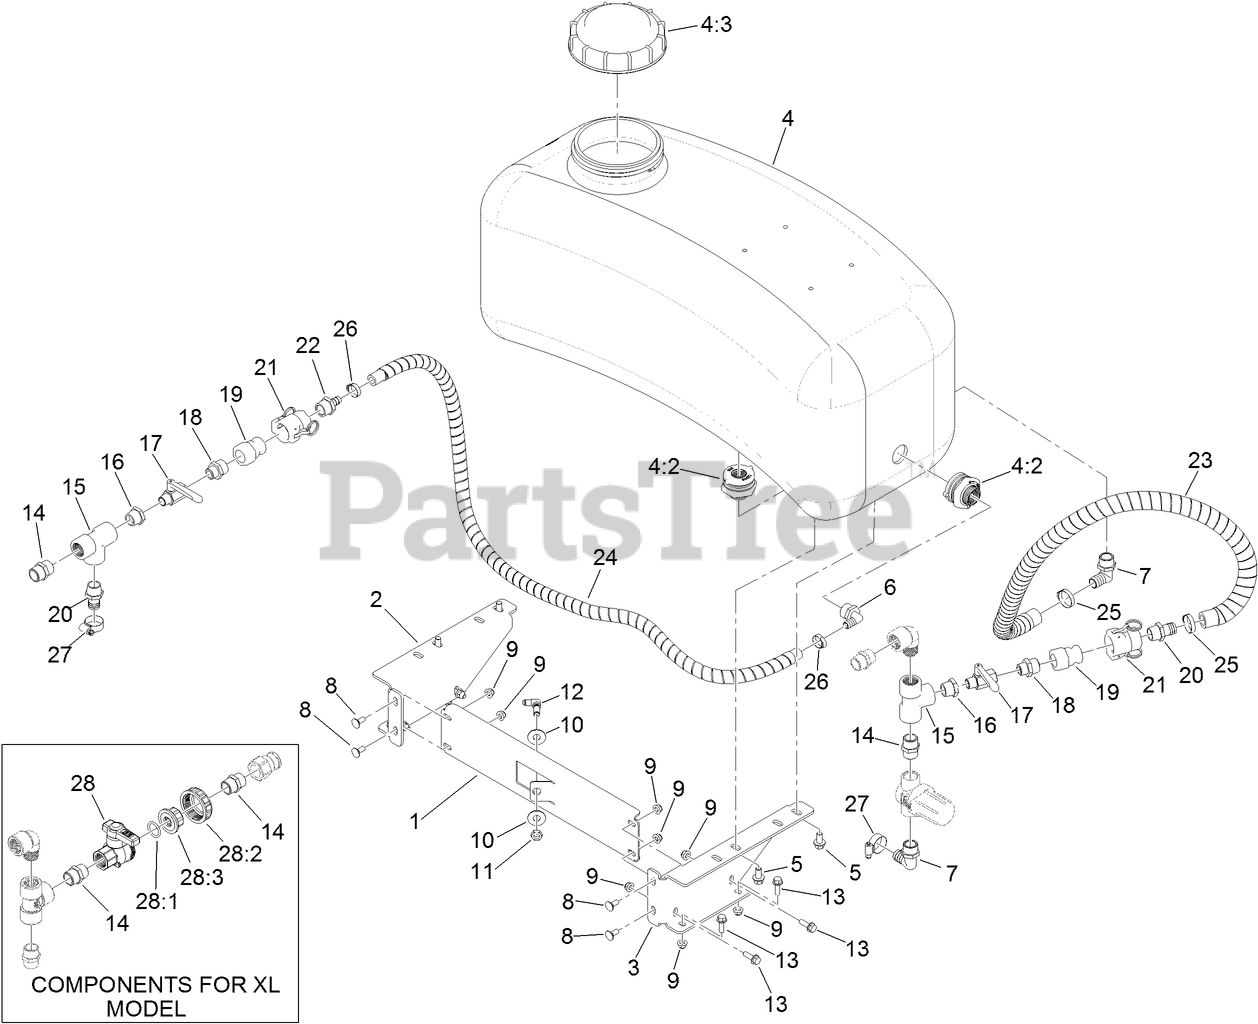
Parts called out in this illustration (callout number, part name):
1	MOUNT-TANK, AUX FRONT
2	MOUNT-TANK, LT AUX
3	MOUNT-TANK, RT AUX
4	ASM-TANK, 30 GAL
4:2	FITTING-BULKHEAD
4:3	CAP-TANK, SPRAY
5	SCREW-HHF
6	FITTING-ELBOW, 90
7	FITTING-ELBOW, 90
8	SCREW-CARR
9	NUT-HEX FLANGE
10	WASHER
11	NUT-JAM
12	FITTING-ELBOW, 90
13	SCREW-HHF
14	FITTING-NIPPLE
15	FITTING-TEE
16	REDUCER-BUSHING, PLASTIC
17	VALVE-CHROME, 1/2
18	FITTING-NIPPLE
19	ADAPTER-MALE
20	HOSEBARB
21	COUPLER-FEMALE
22	FITTING-STRAIGHT
23	HOSE-SPRAY, WRAPPED
24	HOSE-SPRAY, WRAPPED
25	CLAMP-OETIKER, 167
26	CLAMP-OETIKER, 167
27	CLAMP-HOSE
28	VALVE-UNION, 3/4
28:1	O-RING
28:2	RING-VALVE, UNION 3/4
28:3	ADAPTER-UV, 3/4
